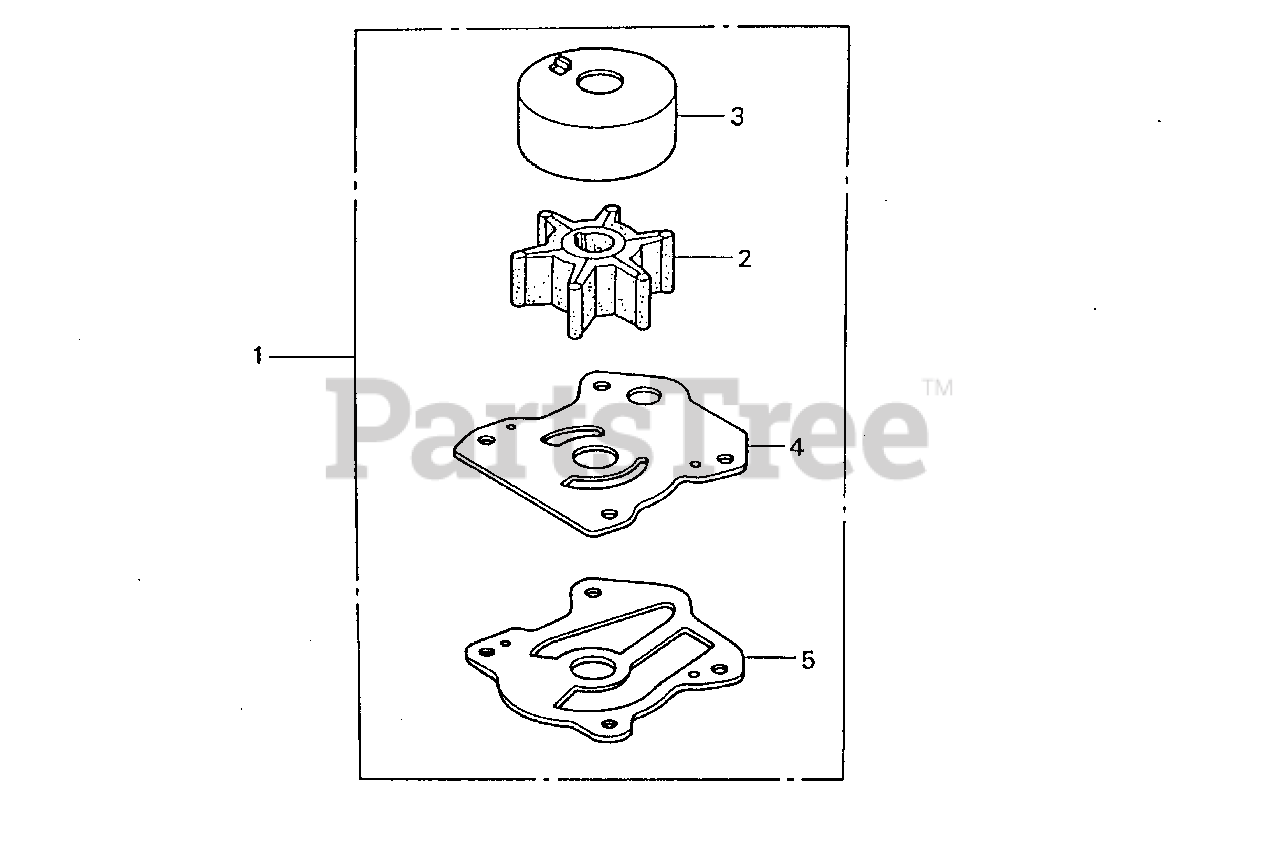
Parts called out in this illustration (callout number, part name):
1	IMPELLER KIT, PUMP
2	IMPELLER, PUMP
3	LINER, PUMP
4	COVER, IMPELLER
5	GASKET B, IMPELLER
